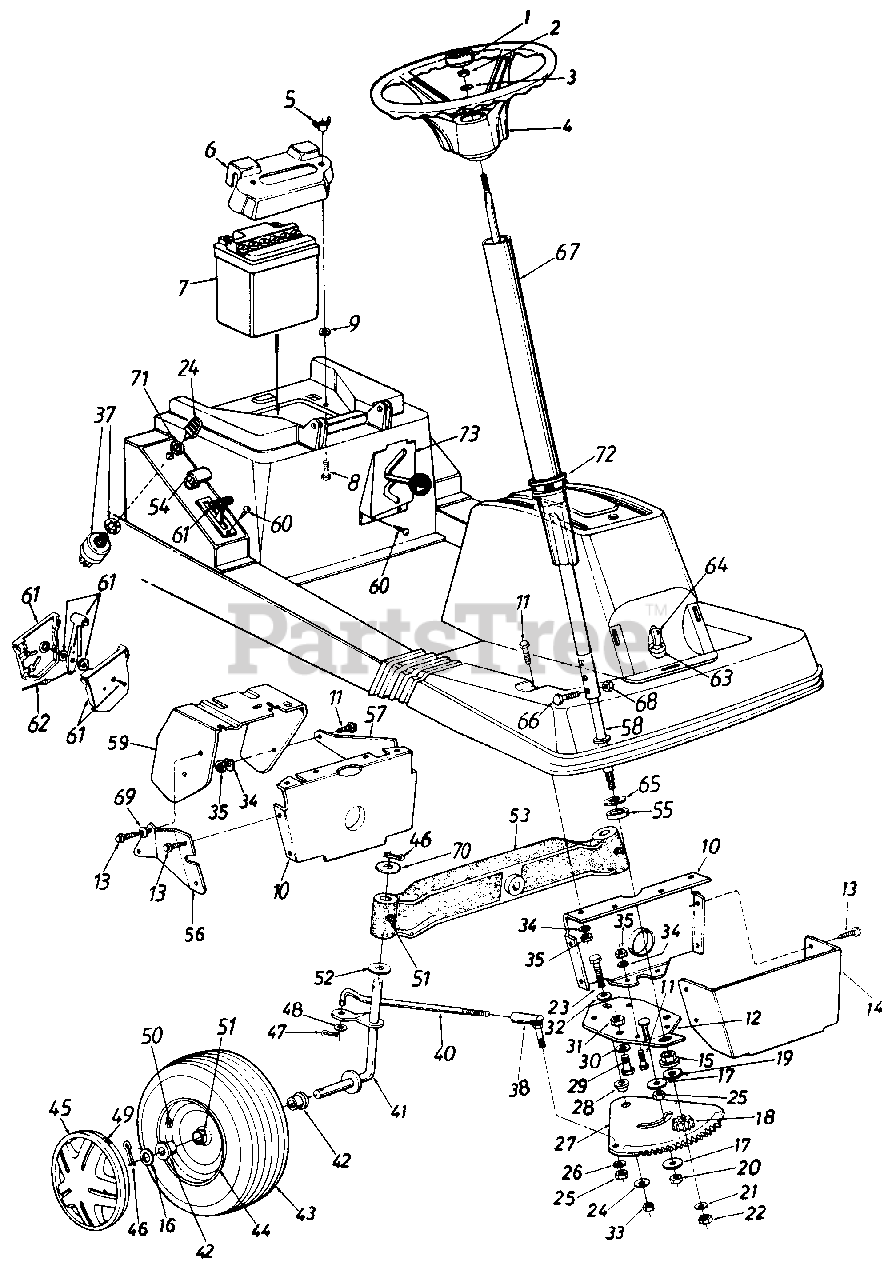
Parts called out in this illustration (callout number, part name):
1	Steering Wheel Cap
2	Hex L-Nut 5/16-24 Thd.
3	Bell-Wash. .345" I.D. x .88" O.D.
4	Steering Wheel Ass'y.
5	Wing Nut 1/4-20 Thd. (Nylon)
6	Battery Hold Down Cover
7	12V Battery
8	Hex Bolt 1/4-20 x 1.75" Lg.
9	Push On Retaining Ring
12	Steering Gear Support Brkt. Ass'y.
13	Hex Wash. Hd. AB-Tap Scr. 1/4 x .62" Lg.
16	Fl-Wash. .635" I.D. x 1.585"
17	Fl-Wash. .385" x 1.37" O.D.
18	Steering Pinion Gear
19	Fl-Wash. .510" I.D. x 1.0" O.D.
20	Hex L-Nut 3/8-24 Thd.
21	Fl-Wash. .34" I.D. x .68" O.D.
22	Hex Nut 5/16-24 Thd.
23	Hex Bolt 3/8-24 x 1.5" Lg. (Gr. 5)
24	Ignition Key Set
25	Hex Nut 3/8-24 Thd.
26	L-Wash. 3/8" I.D.
27	Steering Gear Segment
28	Shld. Spacer
29	Hex Bolt (Nylon) 1/2-13 x .75"
30	Fl-Wash. .53" I.D. x .93" O.D.
31	Hex Nut 1/2-13 Thd.
32	Bell-Wash. .385" I.D. x .88"
34	L-Wash. 5/16" I.D.
35	Hex Nut 5/16-18 Thd.
37	Ignition Switch
38	Ball Joint Ass'y.
40	Steering Tie Rod
41	Front Axle Ass'y.-R.H.
42	Wheel Bearing
46	Cotter Pin 1/8" Dia. x 1.25" Lg.
47	Cotter Pin 1/8" Dia. x 1.0" Lg.
48	Fl-Wash. .385" I.D. x .87" O.D.
49	Spring Clip
50	Air Valve
51	Grease Fitting
52	Fl-Wash. .76" I.D. x 1.49" O.D.
55	Spacer .985" I.D. x 1.25"
61	Throttle Control Box Ass'y.
62	Throttle Control Wire 26" Lg.
63	Headlight Socket
64	Lamp
65	Fl-Wash. .64" I.D. x 1.24"
66	Hex Bolt 1/4-20 x 1.25" Lg.
67	Steering Shaft Ass'y.
68	Hex L-Nut 1/4-20 Thd.
69	Bell-Wash. .345" I.D. x .88" O.D.
70	Fl-Wash. .75" I.D. x 1.5" O.D.
71	Ignition Switch Nut
72	Steering Cover Brg.
73	FNR Index Brkt.
